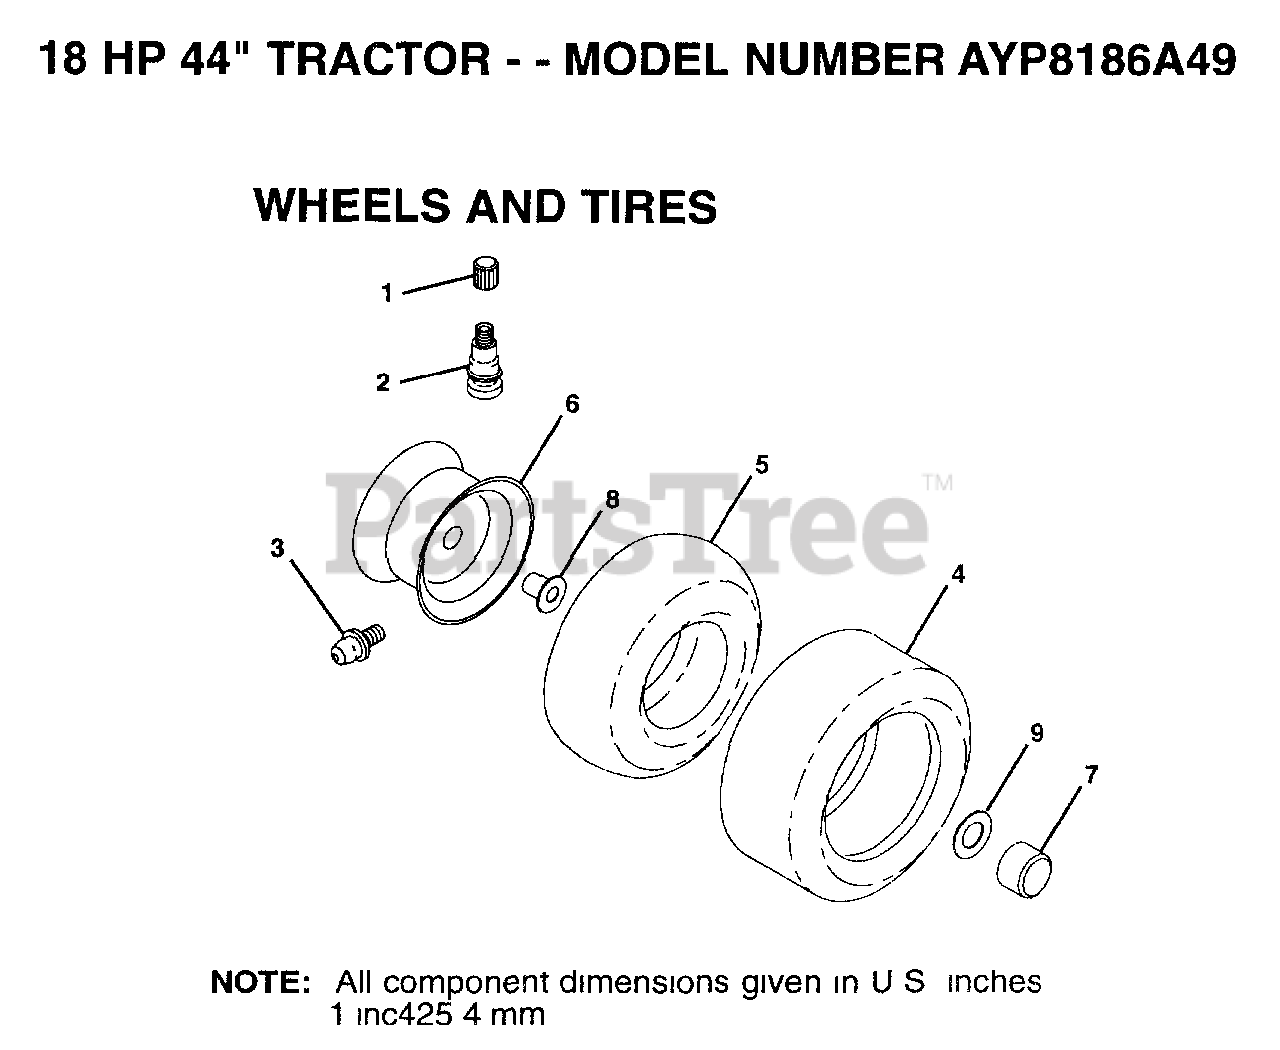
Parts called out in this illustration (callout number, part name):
1	VALVE CAP
2	VALVE STEM LT
3	FITTING LT
5	TUBE.5.3/4.5/6
5	TUBE.23X8/10-12
6	"RIM ASM 8"" FRT"
6	"RIM ASM 12"" REAR"
7	HUB CAP
8	"FLANGE, BEARING"
9	WASHER
